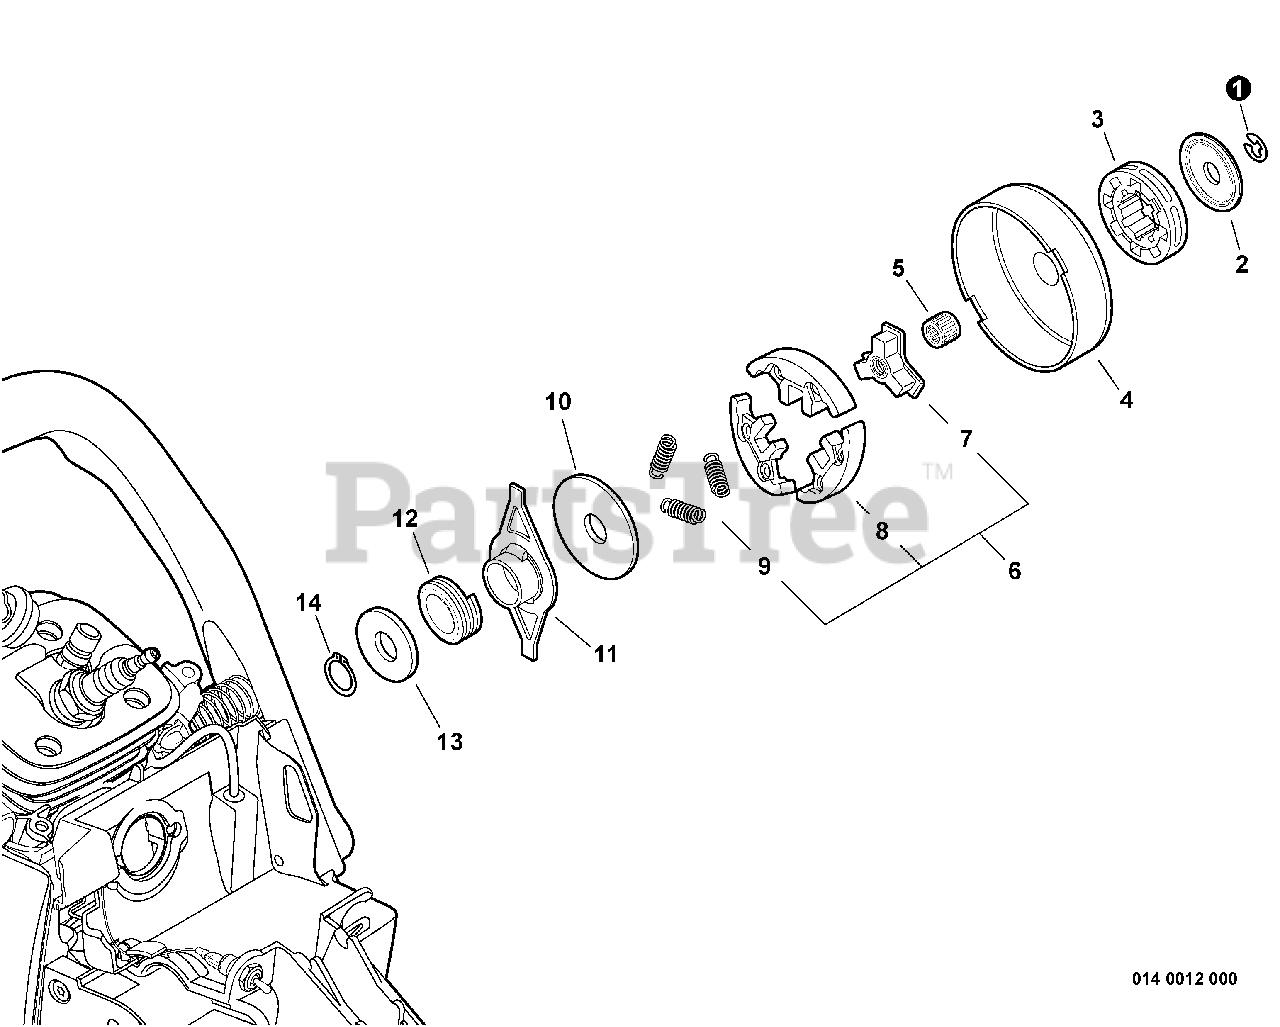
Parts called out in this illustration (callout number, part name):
1	RING, SNAP Ø8 T: 1.2
2	WASHER 10×28.5×3.5(0.8)
3	SPROCKET, RIM 3/8"×7T
4	DRUM, CLUTCH
5	BEARING, NEEDLE 10
6	CLUTCH ASSY
7	HUB, CLUTCH
8	SHOE SET, CLUTCH (3PCS)
9	SPRING, TENSION
10	PLATE, CLUTCH
11	COLLAR 15×19×73
12	GEAR, WORM
13	WASHER 15.5×22.5×0.5
14	RING, RETAINING 15
